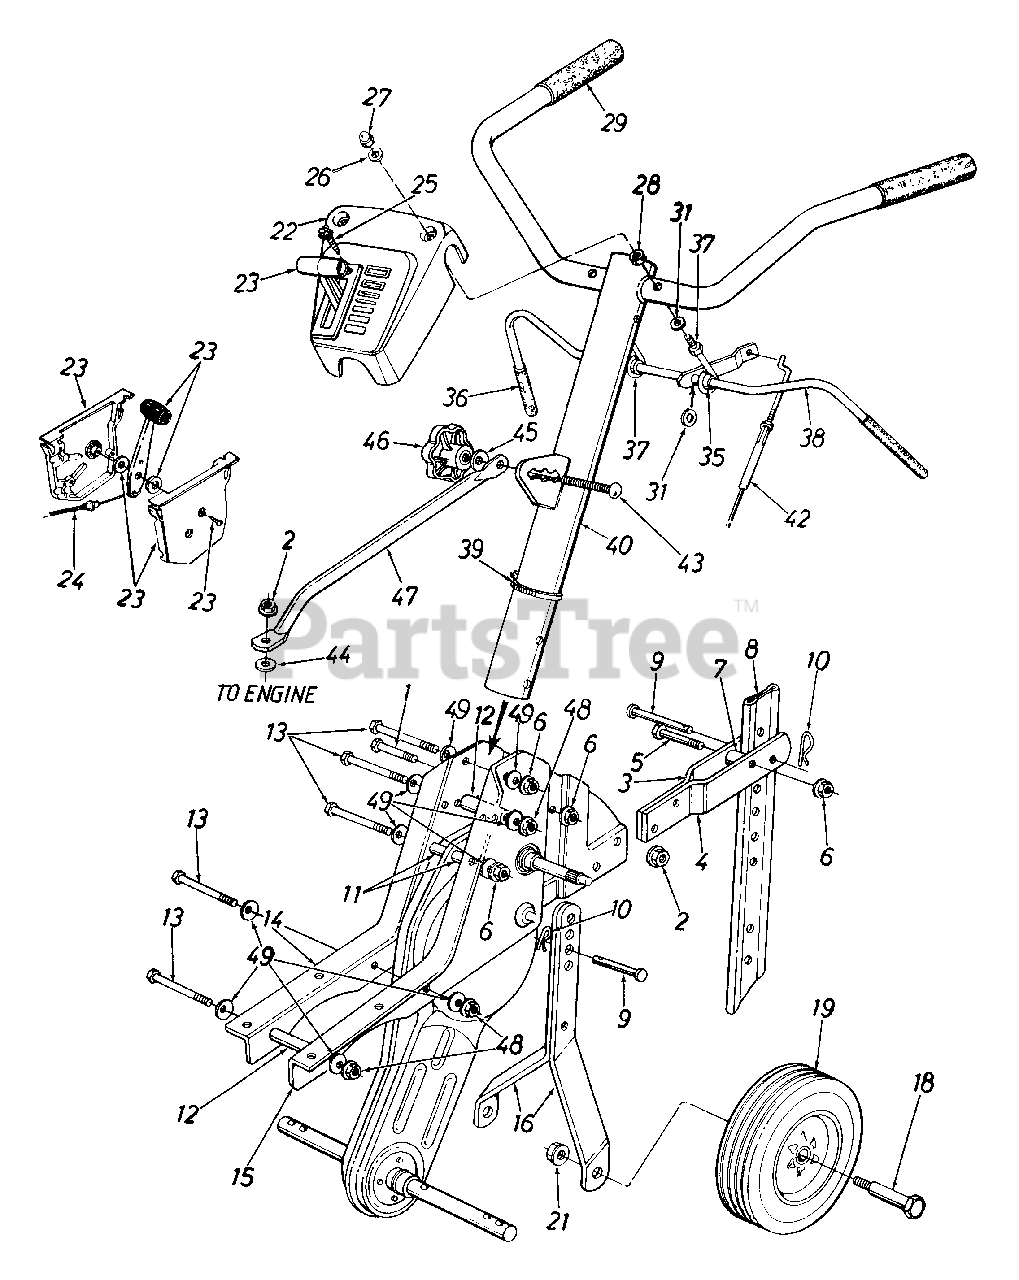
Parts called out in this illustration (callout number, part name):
1	Hex Bolt 5/16-18 x 1.25" Lg.
2	Hex Flange L-Nut 5/16-18 Thd. (Gr. 5)
3	Tail Piece Brkt. (R.H.)
4	Tail Piece Brkt. (L.H.)
5	Hex Bolt 5/16-18 x 1.5" Lg.
6	Hex Flange L-Nut 5/16-18 Thd. (Gr. 5)
7	Spacer .32" I.D. x .75" O.D.
8	Depth Bar
9	Clevis Pin .375" I.D. x 1.75" Lg.
10	Internal Cotter Pin
11	Spacer .326" I.D. x .47" O.D.
12	Spacer.322" I.D. x .44" O.D.
13	Hex Bolt 5/16-18 x 2.75" Lg.
19	Wheel Ass'y.
20	Hex Bolt 3/8-16 x 1" Lg. (Gr. 8)
21	Hex Flange L-Nut 3/8-16 Thd. (Gr. 5)
22	Handle Cover
23	Throttle Control Box Ass'y
24	Throttle Control Wire 30.5" Lg.
25	Truss Mach AB-Tap Scr #10 x .5" Lg.
26	Fl-Wash .266" I.D. x .625" O.D.
27	Hex L-Stop Nut 1/4-28 Thd.
28	Hex Nut 1/4-28 Thd.
29	Grip - Handle
31	Fl-Wash. .385" I.D. x .62" O.D.
35	Plastic Bushing .38" I.D.
36	Grip - Clutch
37	Clutch Handle Eye Bolt
43	Carr. Bolt 5/16-18 x 1" Lg. (Special)
44	Fl-Wash .344" I.D. x 1.12" O.D.
45	Bell-Wash .345" I.D. x .88" O.D.
46	Hand Knob
49	Bell-Wash .345" I.D. x .88" O.D.
